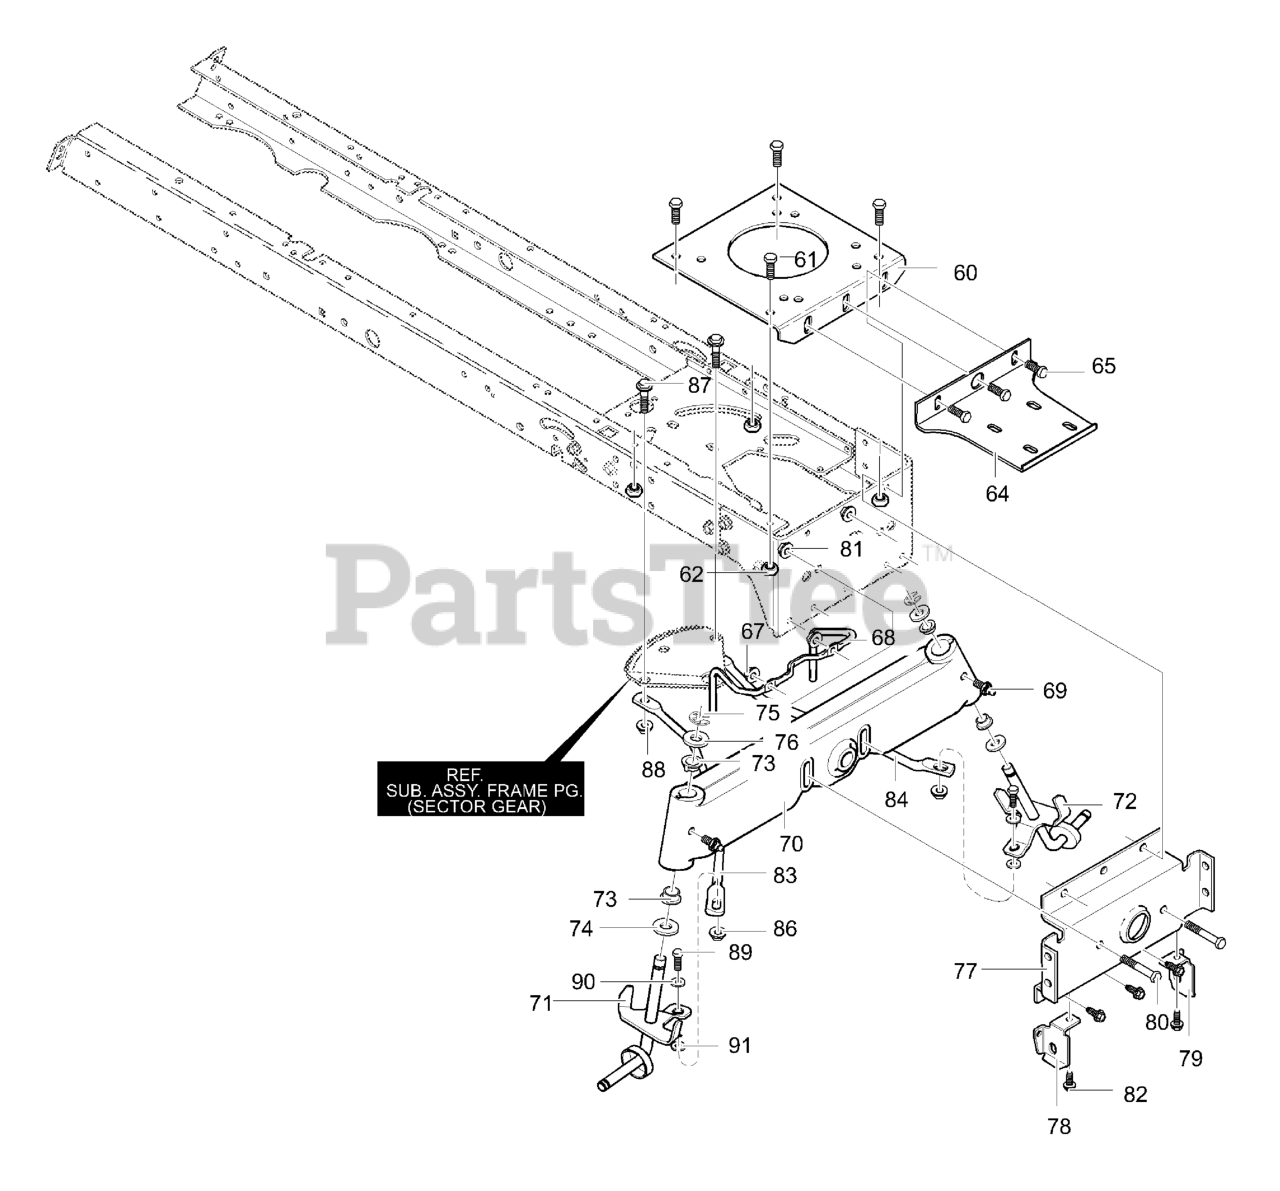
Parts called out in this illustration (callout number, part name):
60	Engine Plate
61	Screw, .312-18x.75
62	Nut, 5/16-18
64	Bracket, Muffler Mount
65	Screw, .312-18x.75
67	Nut, 5/16-18
68	Guide-Stack Pulley Belt
69	Zerk, Grease
70	Axle, Cast Machined
71	Spindle, Long RH
72	Spindle, Long LH
73	Bearing, Spindle
74	Washer, .766IDx1.62ID
76	Washer, Flat
77	Hanger, Axle
78	Hanger, Deck RH
79	Hanger, Deck LH
80	Screw, 5/16-18 x 3.00
81	Nut, 5/16-18
82	Screw, .312-18x.75
83	Drag Link, RH
84	Drag Link, LH
86	Nut, 3/8-16
87	Shoulder Bolt
88	Nut, 3/8-16
89	Screw, 3/8-16 x 1.50
90	Flatwasher
91	Flatwasher
